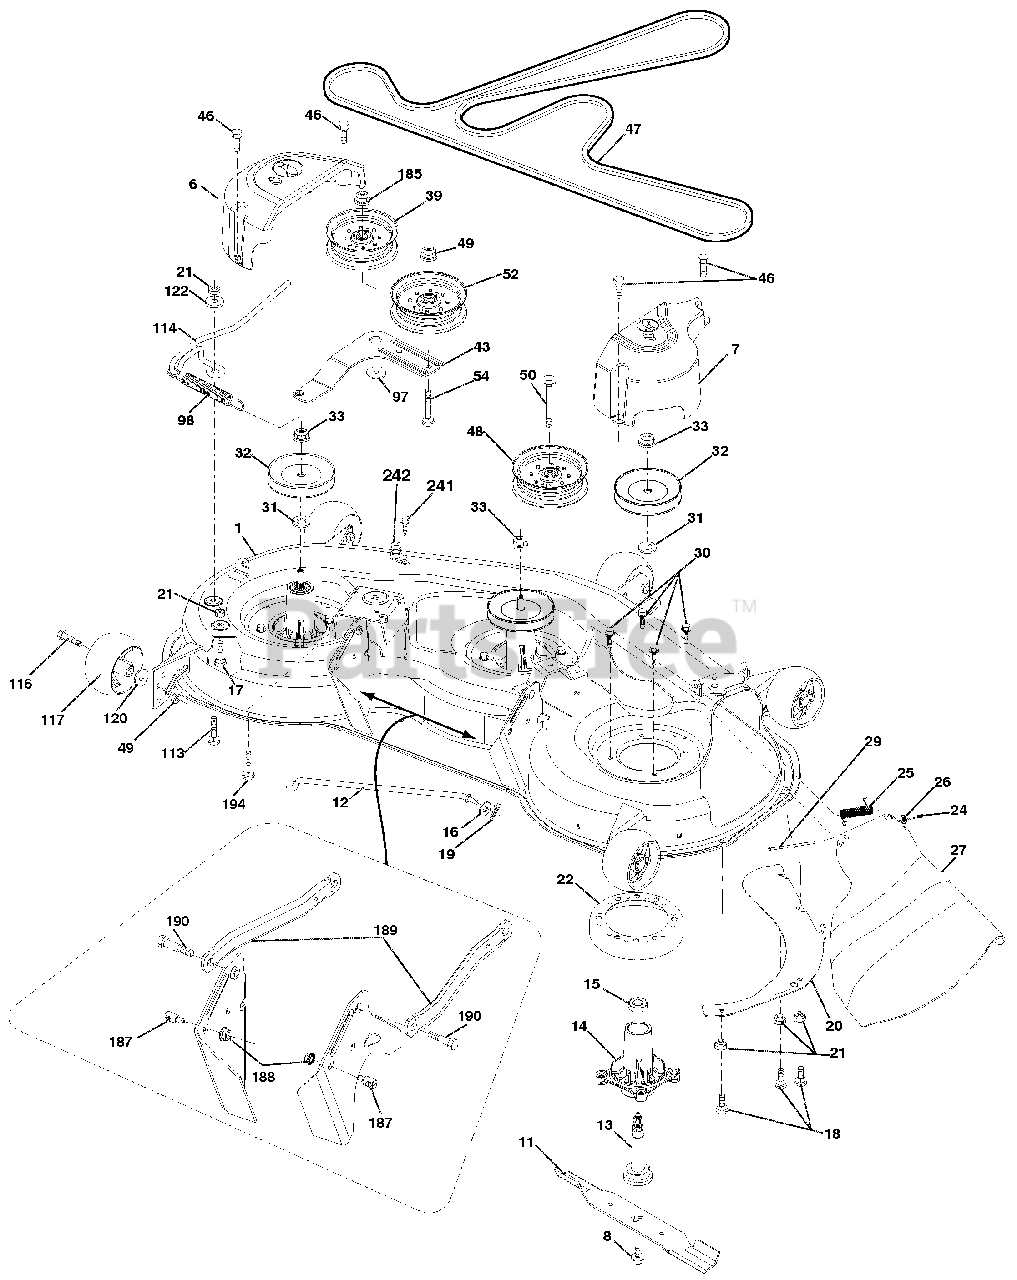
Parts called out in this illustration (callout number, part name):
6	COVER MANDREL LH
7	COVER MANDREL RH
8	BOLT/WASHER ASM.7/16-20.UNF
11	48" BAGGER BLADE
11	BLADE, MULCH 42" 16.75"
12	ROD.ANTI SWAY.48/54"K46.TEX
13	SHAFT ASM.MANDREL.48/54"SVC
14	HOUSING.MANDREL.4PT.SERVICE
15	BEARING.BALL.MANDREL
16	Washer 13/32 x 13/16 x 12 Ga.
17	BOLT.CARR.5/16-18 X 5/8 SHORT
18	BOLT.RDHD.SQNK.5/16-18 X 5/8
19	PIN.COTTER.5/16.BOW TIE LOCK
20	BAFFEL VORTEX
21	Nut, Hex, Crownlock 5/16-18
22	STRIPPER.MANDREL.DECK
24	CAP.SLEEVE..80X.112.BLK.MOWER
25	SPRING.TORSION.48"
26	NUT.PUSH.PHOS.& OIL
27	DEFLECTOR SHIELD
29	ROD.HINGE.42/46"
30	SCREW.THD ROLL.DOD PT.HEX
31	WASHER.SPACER.MANDREL
32	PULLY, MANDREL
32	MANDREL ASM.48/54"
32	(KEY #15)-PULLEY/NUT/WASHER AND BLADE BOLT/WASHER NOT INCLUDED.)
33	NUT.FLANGE.LOCK.TOP
39	PULLEY.IDLER.4.50.HUB.SPECIAL
43	ARM.ILDER
46	SCREW.THD.ROLL.1/4-20 X 5/8
47	PRIMARY MOWER BELT 48"
48	PULLEY.IDLER.4.50.RAW
49	Nut, Hex, Flangelock 3/8-16
50	BOLT RDHD SQNK 3/8-16 UNC X 2
52	PULLEY.IDLER 48"PRIMARY
54	BOLT.CARR.SH.3/8-16X1-1/2.GR5
97	WASHER.FLAT.HARDENED
98	SPRING.DRIVE.DECK.2006
113	BOLT.CARR.5/16-18UNC X 1
114	ROD TENSION RELIEF
116	BOLT.SHOULDER.3/8-16X3-5/8.GR5
117	WHEEL.GAUGE.RALLY.
120	WASHER.13/32 X 1-1/4 X 12 GA.
122	BUSHING.RELIEF.TENSION
185	NUT.LOCK.FLANGE.7/16-14.GR5
187	STUD.FASTNER.W/'D'ANTI-ROTATIO
188	Nut, Lock Hex Flange 5/16-18 u
189	ARM.SUSPENSION.MOWER.REAR
190	BOLT.SHOULDER
194	BOLT CARR SQNK 3/8-16 X 2-1/4
242	PORT WASHOUT
